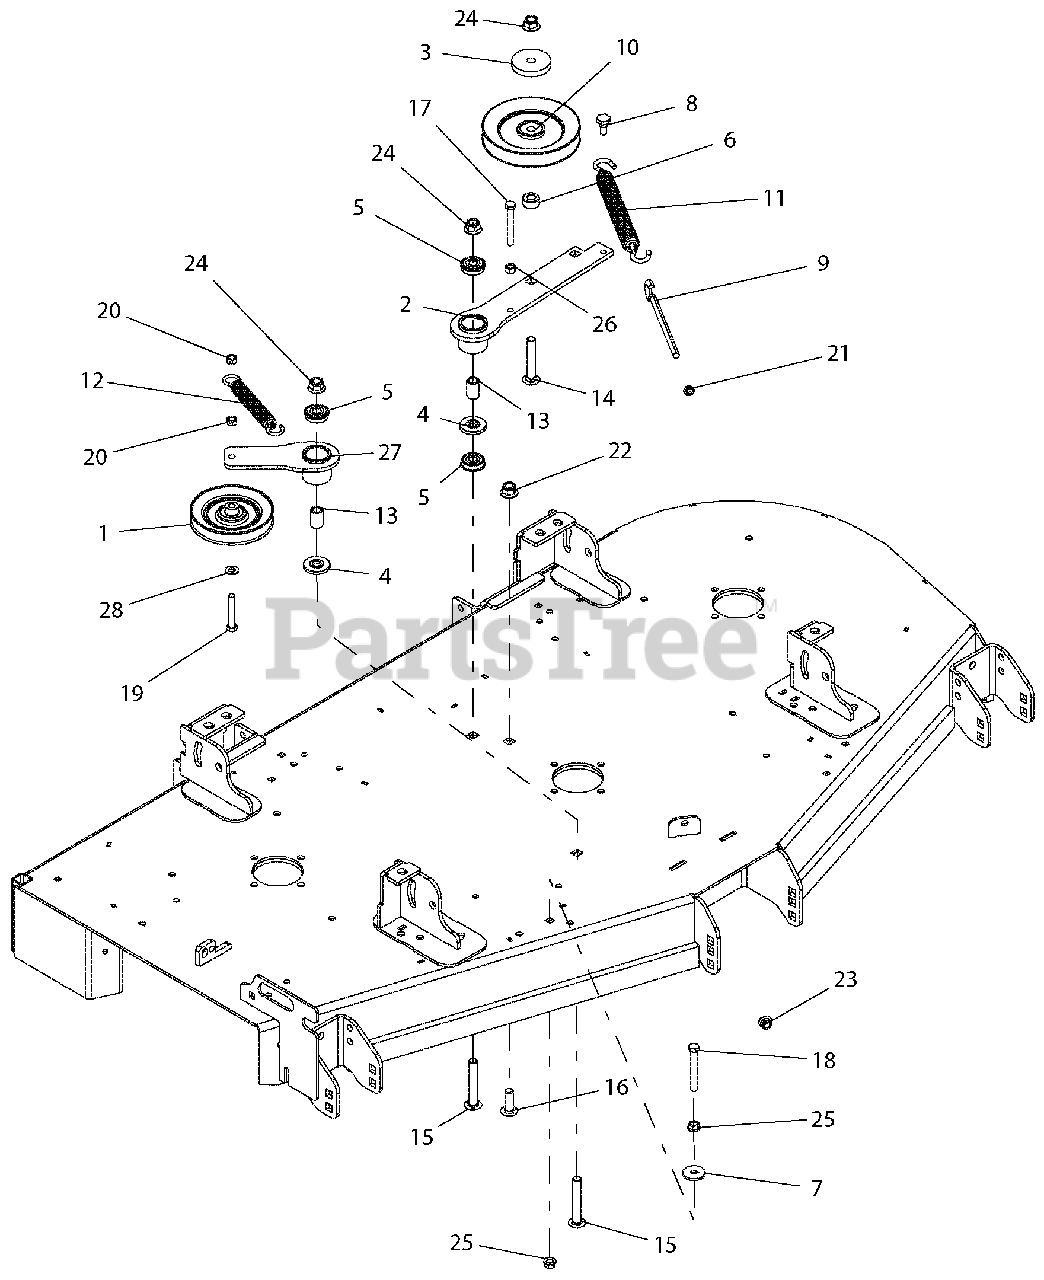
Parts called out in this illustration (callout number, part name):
1	IDLER, V-5.00" W/.69 STANDOFF
2	WLDMT, DECK PTO IDLER ARM-BLACK
3	CAP, IDLER BEARING SEALING
4	SPACER, IDLER ARM
5	BRG, BALL .501 X 1.38 X .438 SEALED
6	BSHG, SPCR .502 X .997.50 PM
7	WSHR-FL-STL .406X1.375X.135 YZ
8	BLT, SHLDR EP .38-16X.30 HEX YZ
9	BOLT, .38-16X6.00 .62 DIA EYE
10	SHEAVE, .50" ID X 6.00" OD V-IDLER
11	SPRG, EXTENSION
12	SPRG, EXTENSION
13	SPACER, .510 X .750 X 1.148
14	BLT-RDHDSQNK .50-13X3.00YG5
15	BLT-RDHDSQSHNK .50-13X3.25 YWZC
16	BLT-RDHDSQSHNK .50-13X1.50 YWZC
17	BLT-HEX .38-16X2.75 GR5 YWZC
18	BLT-HEX .38-16X3.00 GR5 YWZC
19	BLT-HEX .38-16X2.25 GR5 YWZC
20	NUT-LK-CTR .38-16 YWZC
21	NUT, JAM .375-16 YWZC
22	NUT-LK-NYL-FLG .50-13 YWZC
23	NUT-LK-NYL-FLG .38-16 YWZC
24	NUT-LK-NYL-FLG .50-13 YWZC
25	@NUT-SPNLK-FLG .375-16 YWZC
26	NUT-HEX .38-16 YWZC
27	WLDMT, DECK RH IDLER ARM-BLACK
28	WSHR-FL-STL.406X.812X.065 YWZ
